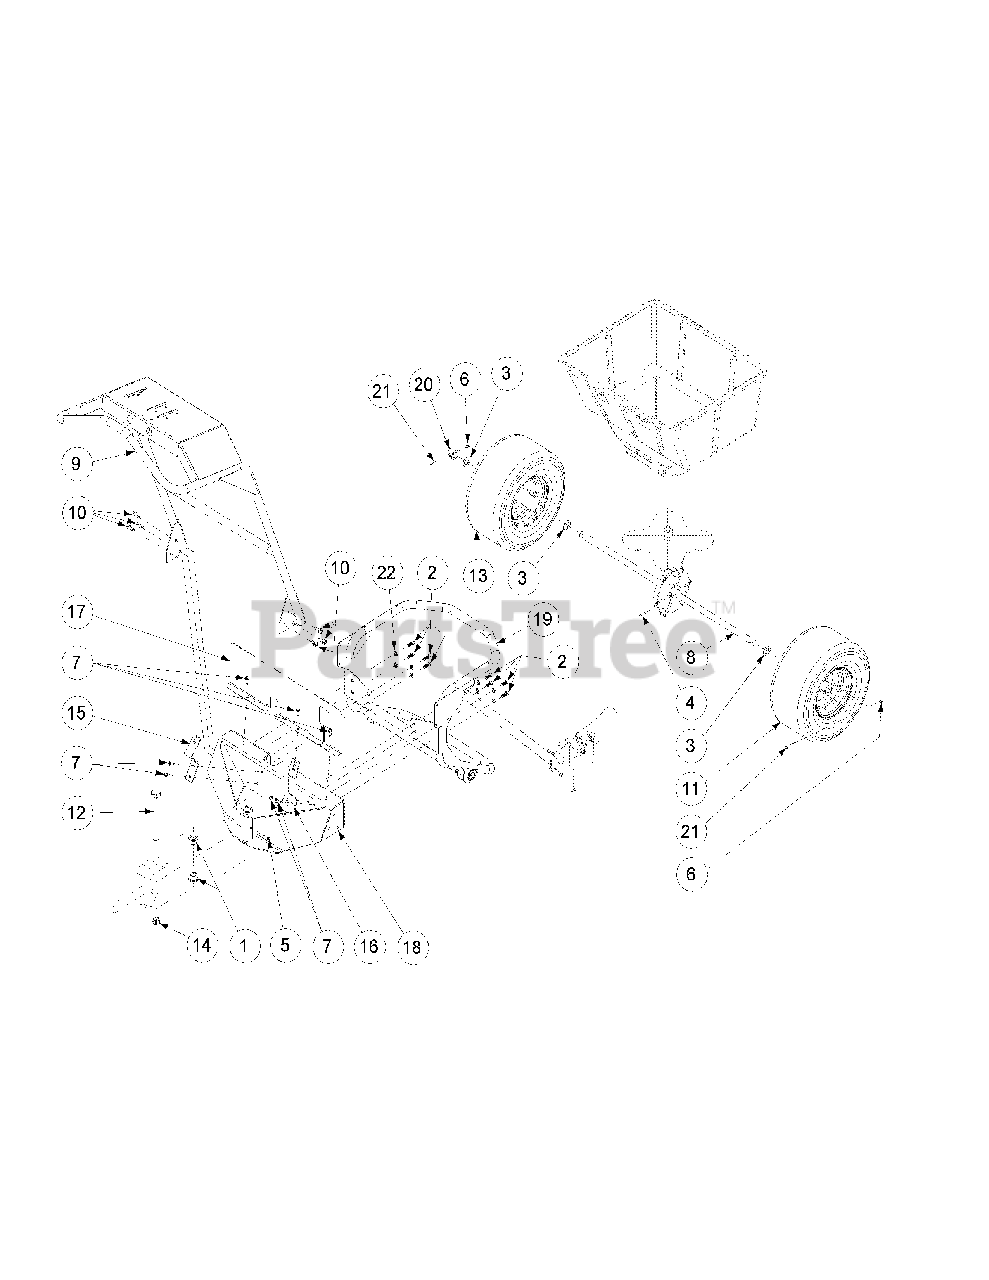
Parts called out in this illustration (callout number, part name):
2	Hex Cap Screw, 5/16-18 x 3/4
3	Washer, .89ID x 1.5OD x .09, SS
4	Roll Pin, 5/32 x 1-1/4, SS
5	Grease Fitting, 1/4-28 x 3/16
6	Nut, #10-24
7	Self Tapping Screw, 1/4-20 x .75
8	Front Axle
9	Handle Weldment
10	Self Tapping Screw, 5/16-18 x .75
11	Drive Wheel Assmebly, 13 x 6.5-6
12	Hex Cap Screw, 3/4-16 x 6.50
13	Idler Wheel Assembly, 13 x 6.5-6
14	Jam Nut, 3/4-16
15	Shut-Off Cable bracket
16	Deflector Cable bracket
17	Shield, SS
18	Pivot Bracket Weldment
19	Front Frame bearing Assembly Includes:
19	Grease Fitting, 1/4-28 x 3/16
19	Axle Bearing
20	Shaft Collar
21	Screw, 10-24 x 1.25
22	Lock Washer, 5/16, SS
